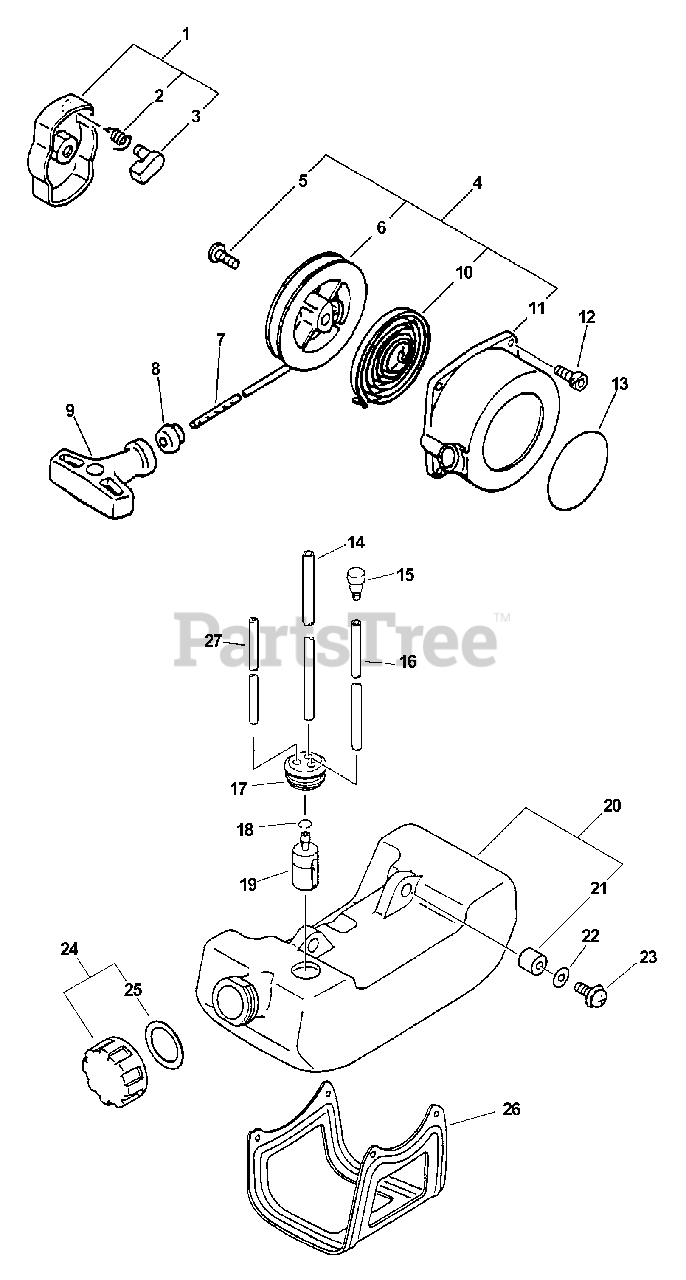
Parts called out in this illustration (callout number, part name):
1	PAWL ASSY, STARTER
2	SPRING, RETURN
3	PAWL, STARTER - BLACK
4	STARTER ASSY, RECOIL
5	SCREW
6	REEL, ROPE
7	ROPE, STARTER 3.0×1000
8	GUIDE, ROPE
9	GRIP, STARTER
10	SPRING, RECOIL
11	CASE, RECOIL STARTER
12	BOLT 4×16
13	LABEL, ECHO
14	PIPE, FUEL 3x-5x-180
15	VENT ASSY
16	PIPE, FUEL 3x-5x-70 BLACK
17	GROMMET, FUEL
18	CLIP 6 MM
19	FILTER, FUEL
20	TANK, FUEL
21	SPACER 6.2×7.8×6
22	WASHER 5.5×12×0.8
23	SCREW 5×16
24	CAP ASSY, FUEL
25	GASKET, FUEL CAP
26	GUARD, FUEL TANK
27	PIPE, FUEL RETURN 3×6×90 MM CLEAR
